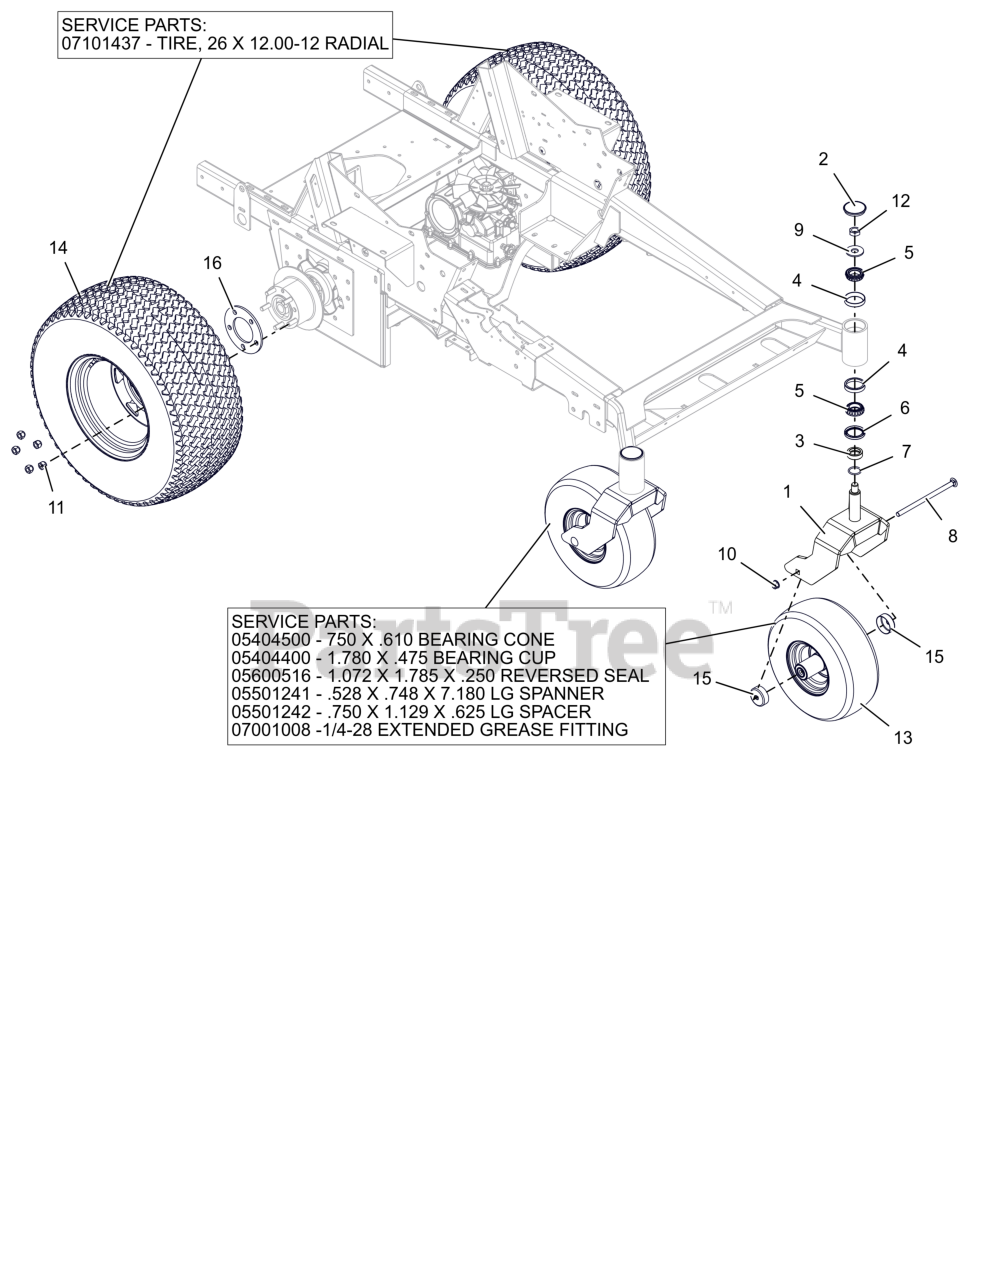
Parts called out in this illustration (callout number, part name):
1	WLDMT, CASTER FORK (RED)
2	CAP, DUST
3	SPCR, FRONT CASTER FORK
4	BRG-CUP 2.328X.465
5	BRG-CONE 1.25X.66
6	SEAL, OIL 1.75 X 2.332 X .312
8	BTL,RHSN .500-13 X 9 G5 ZCC
9	WSHR-FL-STL 0.812X2X0.148 ZCC
10	NUT-LK-CTR-FLG .500-13 GG ZCC
11	NUT, WHEEL .50-20 ZCC
12	NUT, JAM-TOPLOCK .750-16 ZCC
13	ASM, TIRE/WHEEL 15 X 6.00-6 SEMI
13	BRG-CONE .750X.61
13	BRG-CUP 1.781X.475
13	SEAL,1.072X1.785X.250 REVERSED
13	SPANNER, .528X.748X7.18 LG
13	SPACER, .750X1.129X.625 LG
13	GREASE FITTING 1/4-28 EXTENDED
13	TUBE 15X6-6
14	ASM-WHL/TIRE26X12.00-12 RAD BK
14	TIRE- 26 X 12.00-12
15	SHIELD, WHEEL BEARING
16	SPCR, PT600 WHEEL (BLACK)
